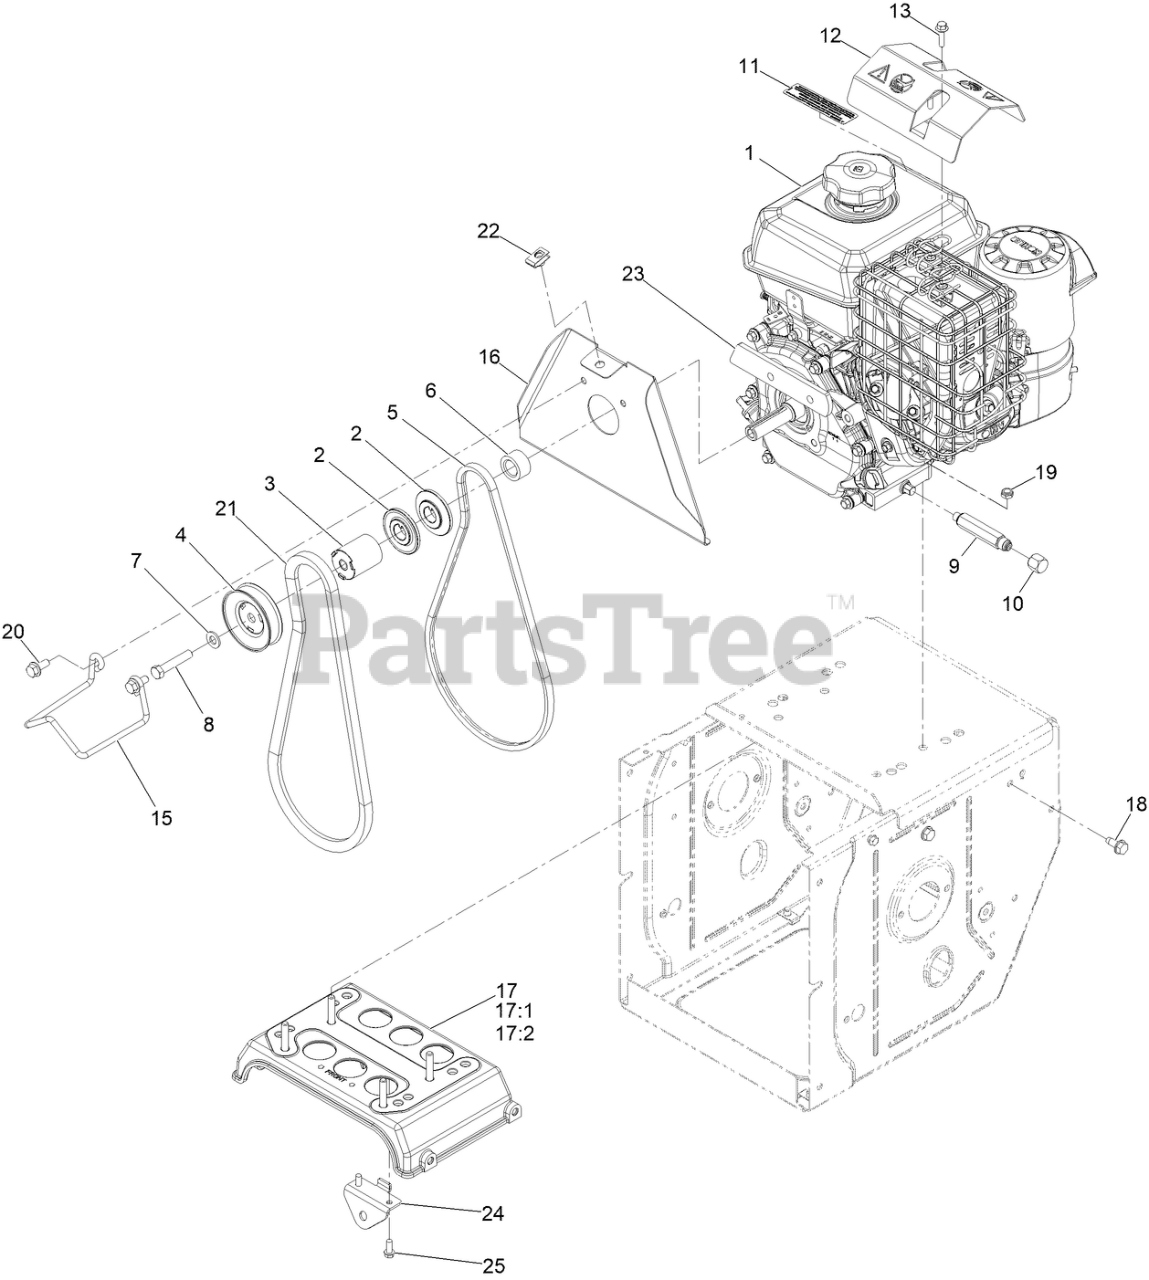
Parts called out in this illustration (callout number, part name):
2	SHEAVE-TRACTION
3	SPACER-PULLEY
4	PULLEY-IMPELLER
5	BELT,3L P21 DRIVE
7	WASHER-FLAT
8	SCREW-HH
9	ADAPTER
11	DECAL-ARRESTOR, SPARK
12	DEFLECTOR-DEBRIS, MUFFLER
13	SCREW-HHF
15	GUIDE-BELT
16	COVER-BELT, BACK
17	ENGINE PLATE ASM (G250)
17:1	PLATE-ENGINE
17:2	STUD-PRESS 95/16-18 X 1.625)
18	Screw-HWH 5/16-18 X 3/4 Tf
19	NUT-HEX
20	SCREW-HH
23	SPACER-COVER, BELT
24	BRACKET-CONTROL, TRACTION
25	SCREW-HWH
